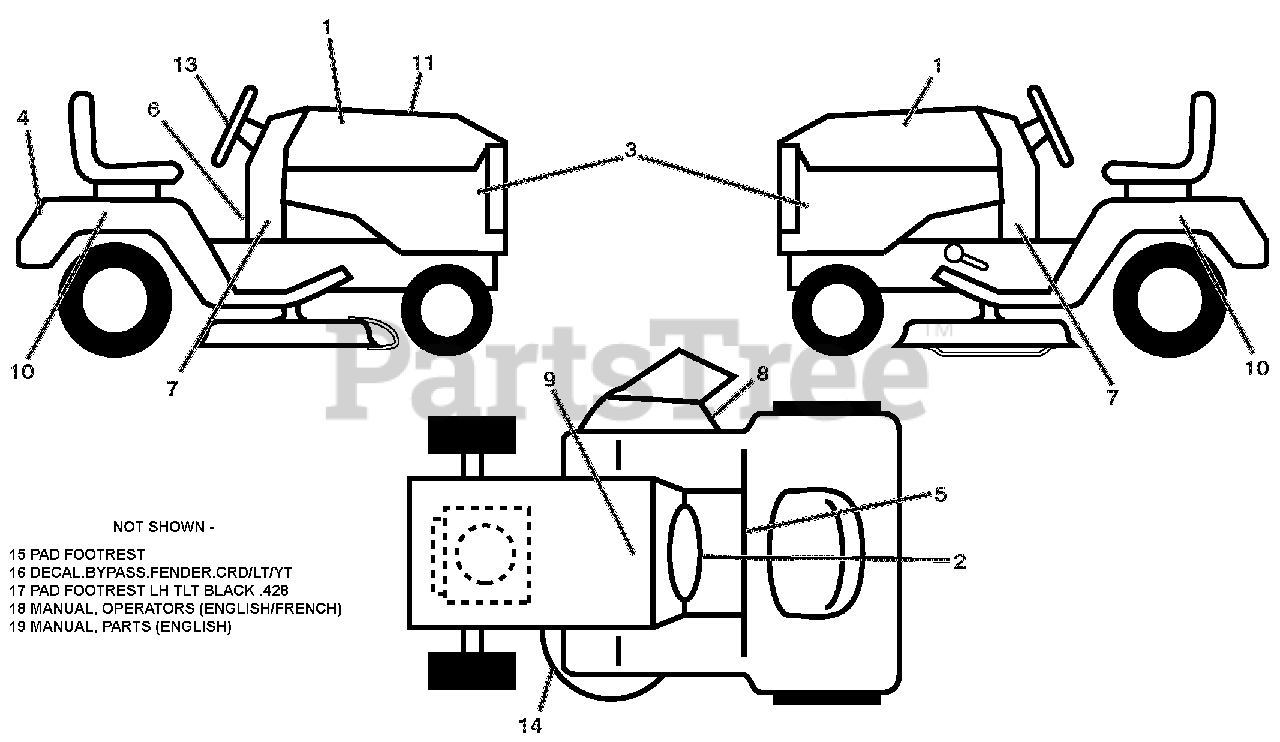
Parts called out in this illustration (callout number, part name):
1	DECAL.HOOD.RH.PRECISION.ARIENS
2	DECAL.FENDER.WARNING.ENG/FR.07
3	DECAL.SDPNL.PWRDBY KOHL.ARIENS
4	DECAL.FENDER.REAR.ARIENS
5	DECAL.FENDER
6	DECAL, WARNING SPARK ARRESTER
7	DECAL DASH LOWER
8	DECAL.MOWER.WARN.KEEP HAND AWY
9	DECAL.BAT.DAN/POI P/L SYM.WPN
10	DECAL.FENDER.SIDE.HYDRO.ARIENS
11	DECAL, REPLACEMENT
13	DECAL.WHEEL.STEER.ARIENS
14	DECAL.V-BELT.SCH.42/46"MEC/ELE
